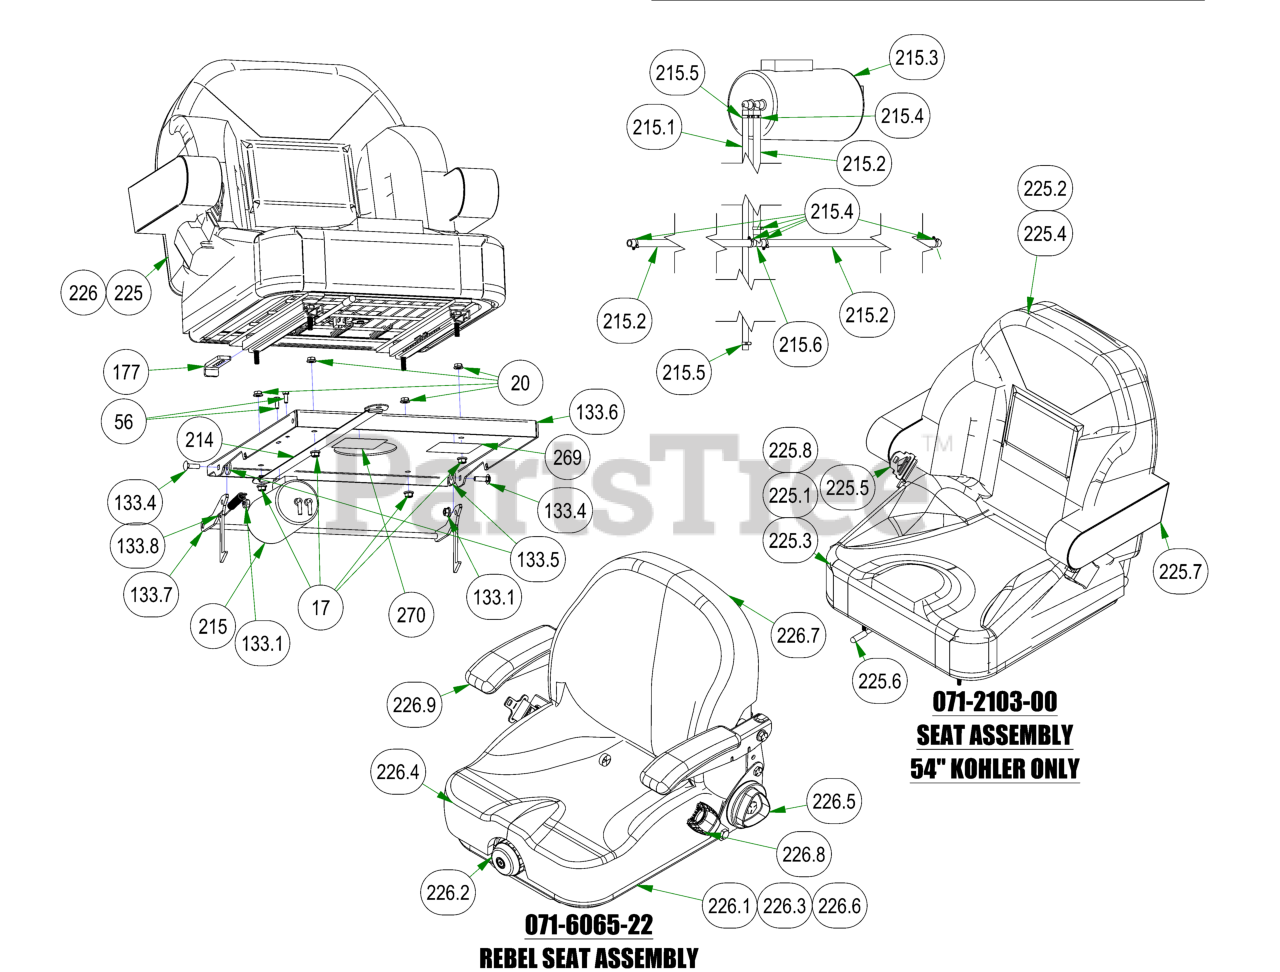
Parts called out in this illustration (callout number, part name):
17	5/16-18 NYLON INSERT FLANGE LOCKNUT ZINC
20	5/16-18 HEX SERRATED FLANGE NUT HARD/ZINC
56	M6-1.0 X 16MM DIN 933 HEX TAP BOLT (CL 8.8) ZINC
133	R-SERIES SEAT PLATE ASSEMBLY
133.1	5/16-18 NYLON INSERT FLANGE LOCKNUT ZINC
133.4	5/16-18 X 1 CARRIAGE BOLT (GR.8) ZINC
133.5	.360 ID X .983 OD X .120 THICK FLAT WASHER NYLON
133.6	R-SERIES SEAT PLATE
133.7	Seat Latch Rod Assembly
133.8	Brake Spring
214	Seat Strap with Buckles
215	2019 Outlaw EPA Cannister Assembly
215.1	3/16" Vinyl Tubing, 66" Long
215.2	1/4" Vinyl Tubing 38" Long
215.3	Carbon Canister
215.4	3/16 Vinyl Clamp
215.5	3/16" Vinyl Hose Clamp
215.6	fuel line T
224	2023 Rebel Frame - Painted
225	2021 Rebel Seat
225.1	Seat Cover for 071-2103-00
225.2	Back Cover for 071-2103-00
225.3	Foam Molded Seat for the 071-2103-00
225.4	Foam Molded back for the 071-2103-00
225.5	Seat Belt Set 071-2103-00
225.6	Seat Rails for Outlaw Seat/2020 ZT Elite/ZTAvenger
225.7	Arm Rest Kit for 071-5060-18
225.8	Set Switch fr 071-5060-18
226	2022 Suspension Seat w/Seatbelt
226.1	4" Single Locking Track Kit
226.2	Weight Adjust Indicator Knob Assy
226.3	Bellows w/Hardware
226.4	Cushion Cover Kit for I3M-Logo
226.5	Recliner Adjustment Knob-New
226.6	Delta Plunger Switch - N.O.
226.7	Back Cover for I3M - Recl - Logos
226.8	2" Retractable Belt Kit w/Spacers
226.9	Set of Armrests-SS Front Adj
269	Control Adj. Control Rod Decal
270	Control Adj. Control Dampener Decal
